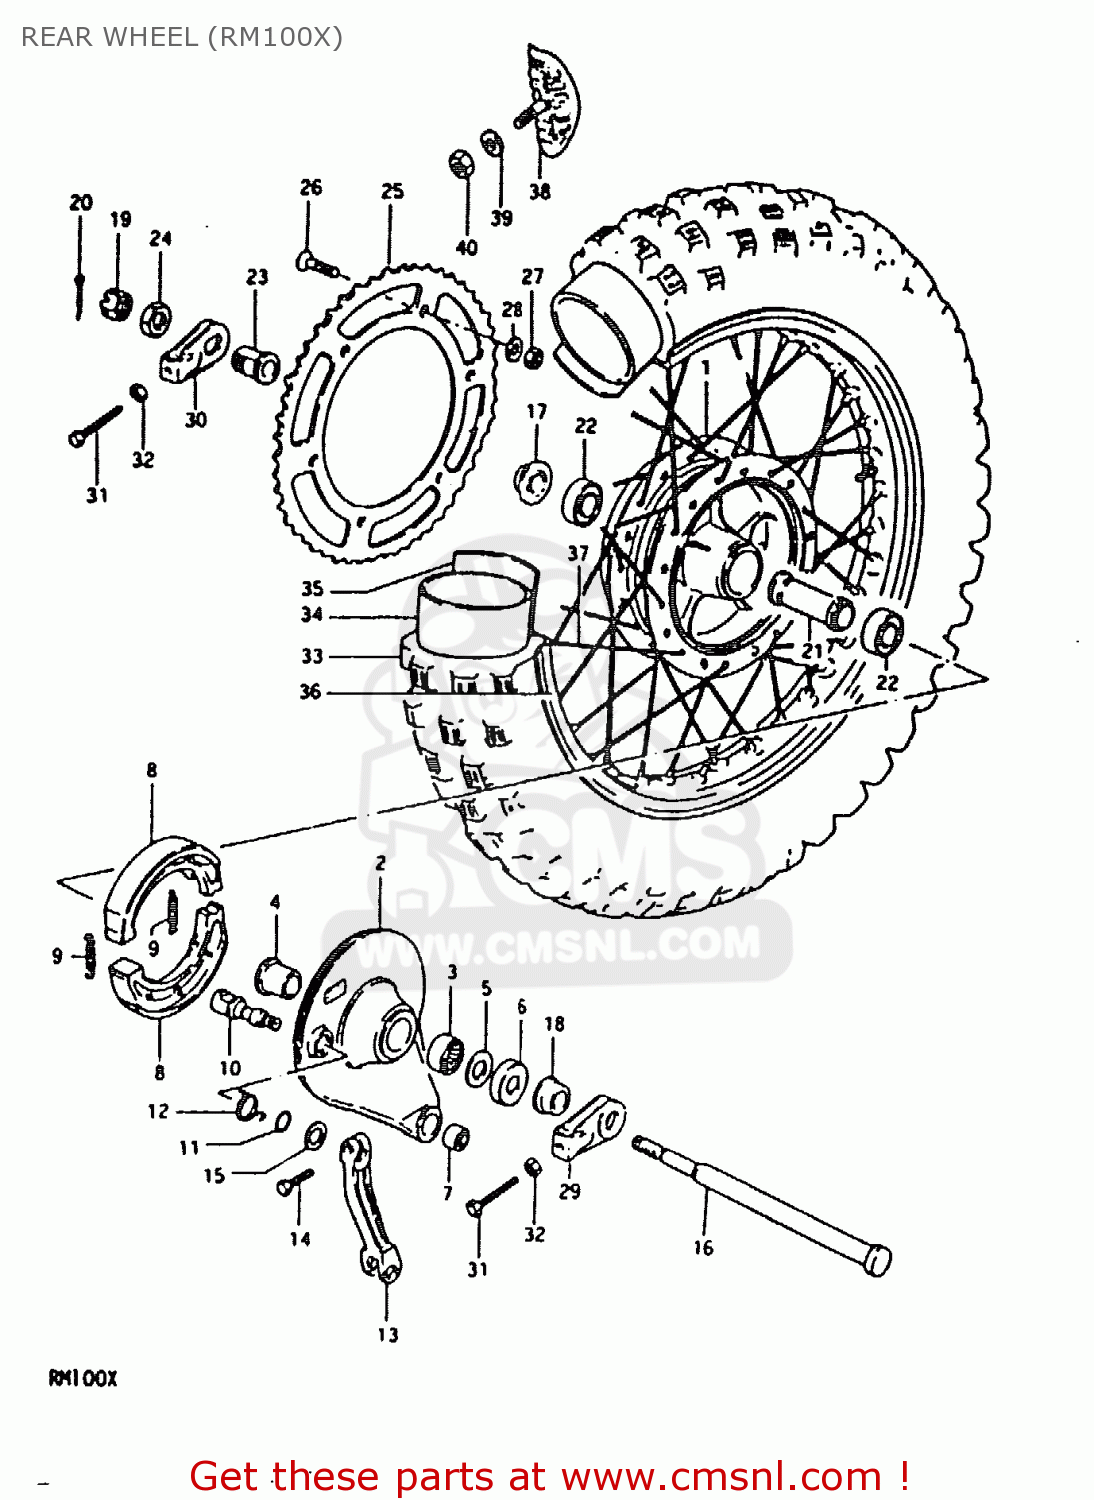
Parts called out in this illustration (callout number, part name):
1	DRUM,REAR HUB
2	PANEL SET,REAR HUB
3	BEARING(22X29X25)
4	SPACER,REAR HUB PANEL
5	WASHER
6	COVER, PANEL DUST SEAL
7	SPHERICAL BEARING,TORQUE
8	SHOE,BRAKE
9	SPRING(L:34)
10	CAM,FR BRAKE
11	O RING(D:2.5,ID:11.4)
12	SPRING
13	LEVER,RR BRAKE CAM
14	BOLT
15	WASHER(12.5X20X1)
16	AXLE,REAR
17	SPACER,RR AXLE,L
18	SPACER (15.2X26X34)
19	NUT 12MM
20	COTTER PIN
21	SPACER,REAR HUB BEARING
22	BEARING
23	SPACER,CHAIN ADJUSTER,L
24	NUT
25	SPROCKET,REAR
26	SCREW(8X33.5)
27	NUT
28	WASHER
29	ADJUSTER,CHAIN
30	ADJUSTER,CHAIN,L
31	BOLT(8X40)
32	NUT
33	TIRE
34	TUBE ASSEMBLY,WHEEL,INNER
35	PROTECTOR,INNER TUBE
36	RIM,REAR WHEEL
37	SPOKE SET,REAR WHEEL
38	STOPPER,BEAD
39	WASHER
40	NUT
